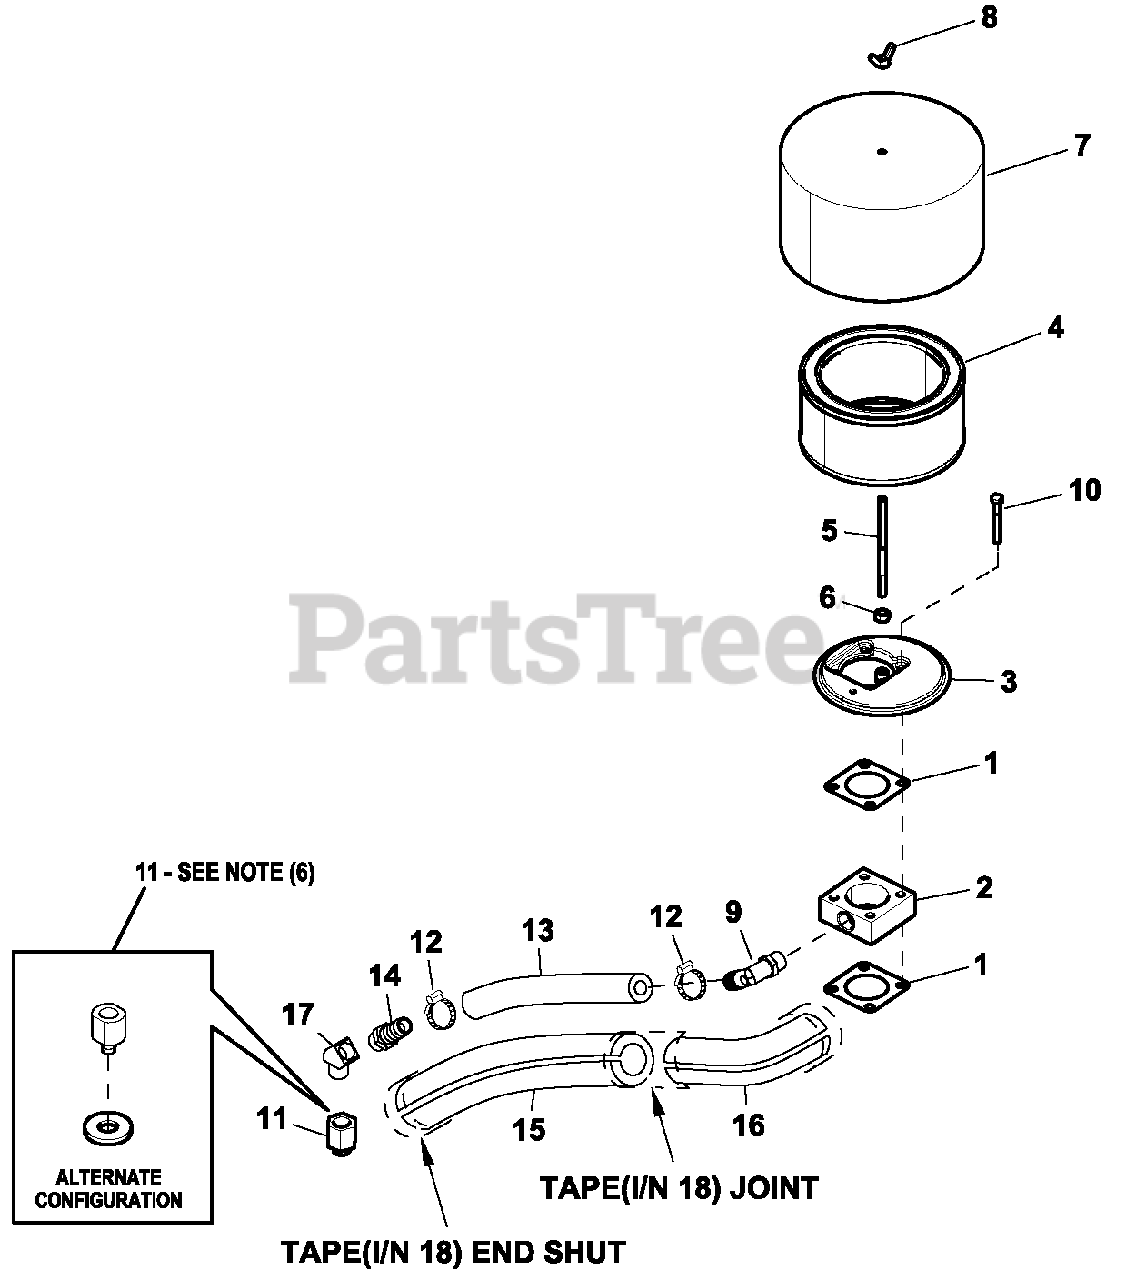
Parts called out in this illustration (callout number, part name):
1	GASKET BOSCH 32 & 40
2	ADAPTOR PCV INTAKE
3	ADAPTOR - CARBURETOR
4	ELEMENT, AIR CLEANER
5	STUDTH 1/4-20X4-1/2 G2ZNC
6	NUT HEX 1/4-20 STEEL
7	PLATE, AIR CLEANER TOP 2.4L
8	NUT WING 1/4-20 W/NY INS ST ZN
9	BARBED EL90D 1/2NPTX3/4
10	SCREW HHC M5-0.8 X 40 G8.8
11	FITTING VENT VALVE COVER
12	CLAMP HOSE #8 .53-1.00
13	HOSE 3/4 ID SAE-30R2 (17.5"LG)
14	BARBED STR 1/2NPTX3/4
15	PIPE INSULATION (17"LG)
16	PIPE INSULATION ELBO
17	ELBOW 45D STREET 1/2NPT BRASS
18	PIPE INSULATION TAPE (14"LG)
